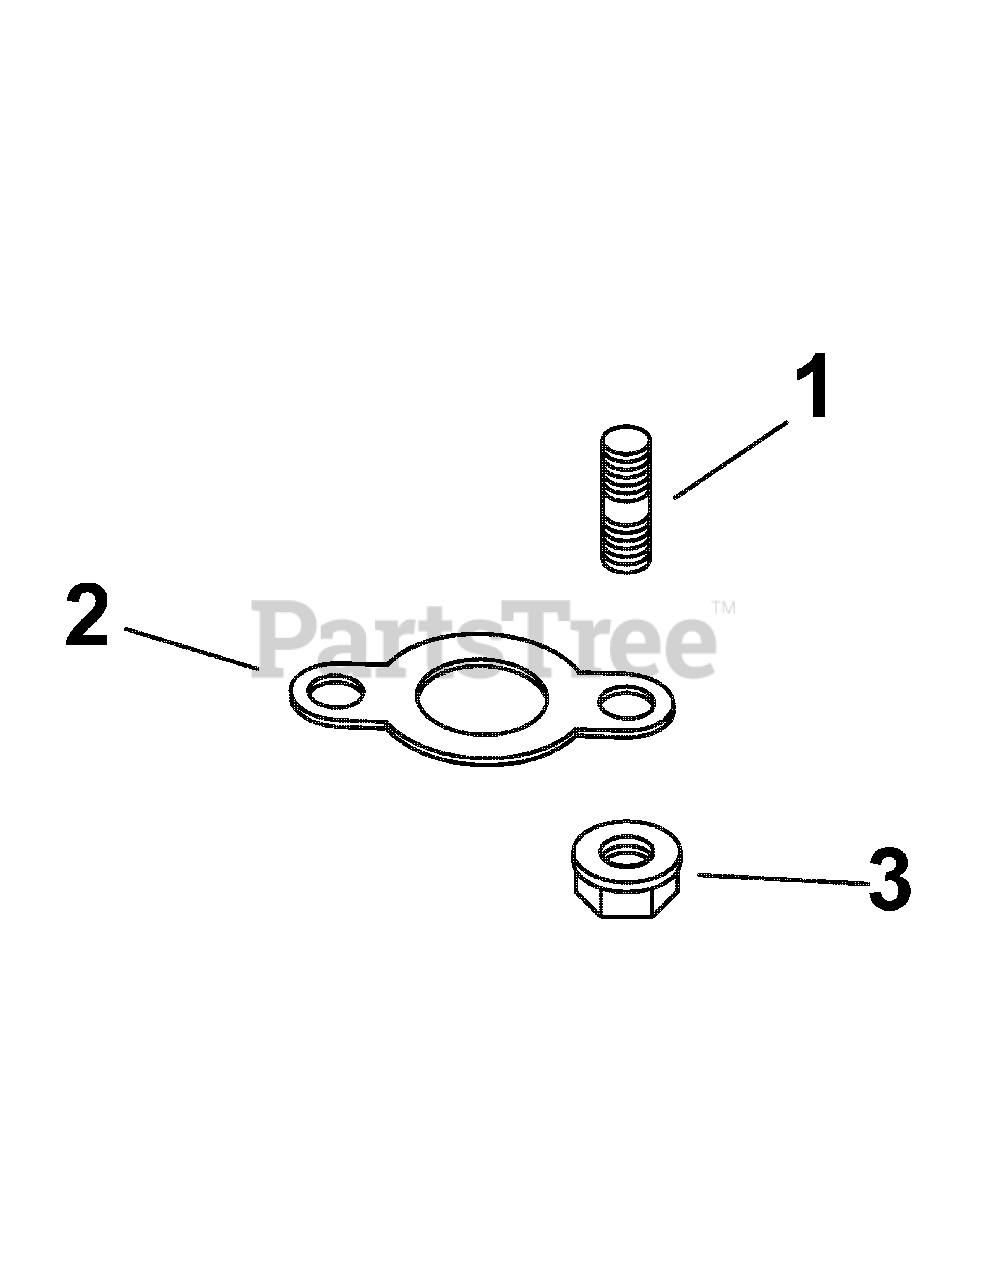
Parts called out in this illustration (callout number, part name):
1	Stud, M8 x 1.25 x 33
2	Gasket, Exhaust
3	Nut, Flg M8 x 1.25
